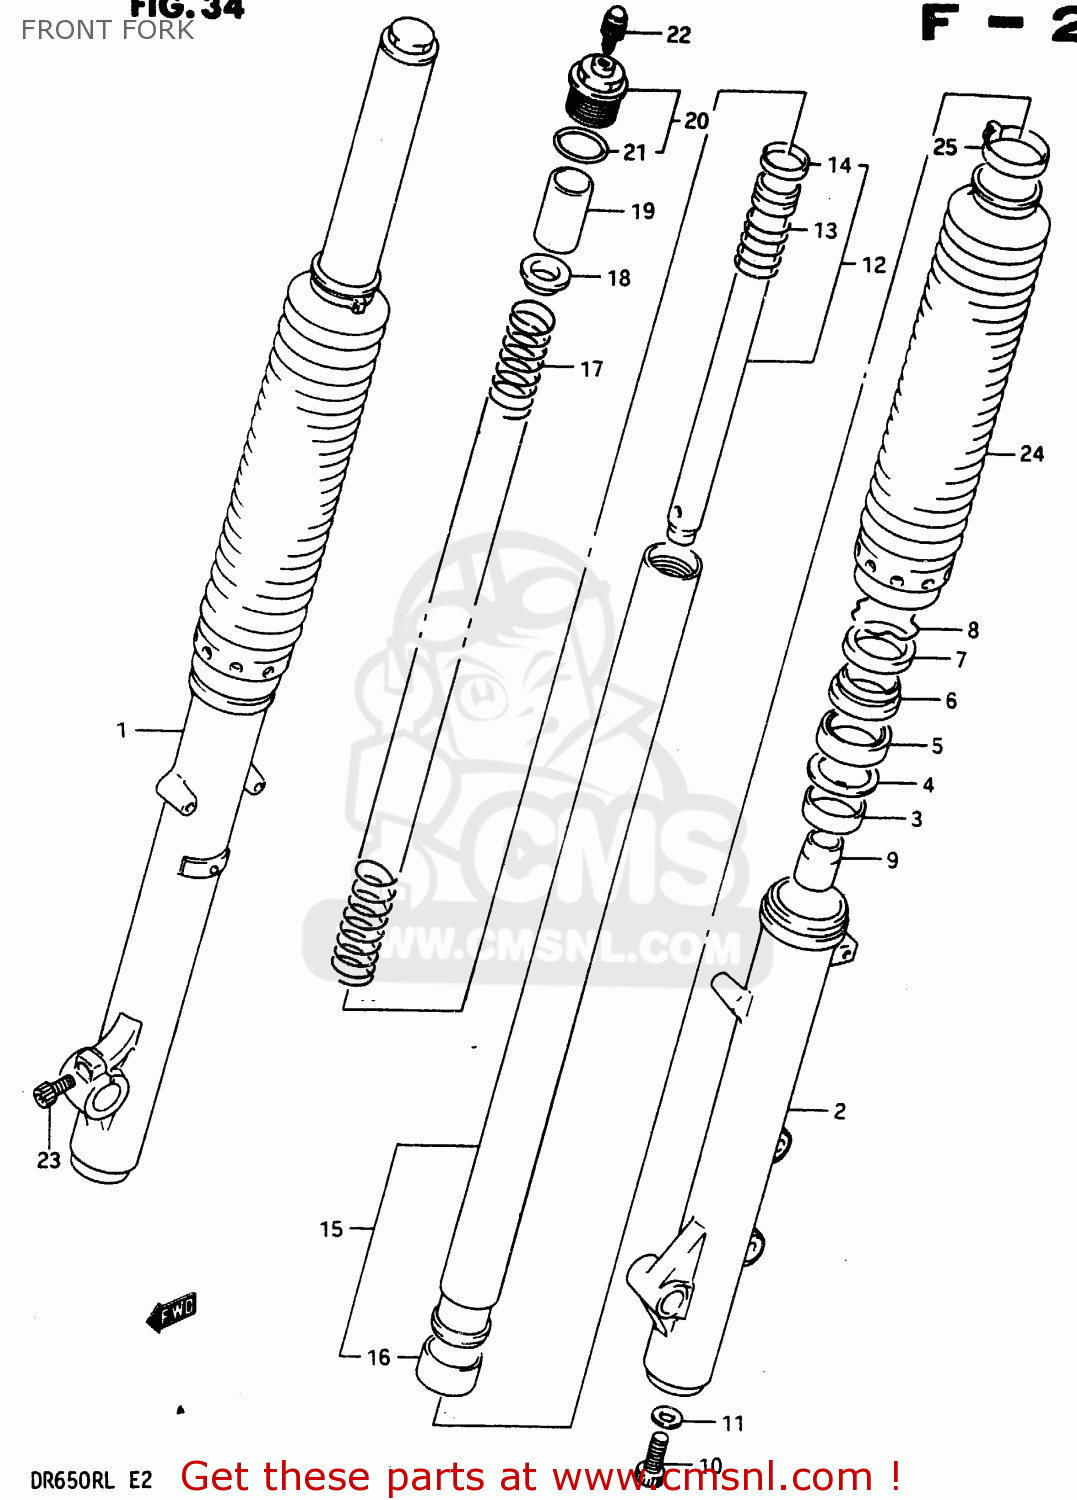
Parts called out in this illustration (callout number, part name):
1	TUBE,OUTER,RIGHT
2	TUBE,OUTER,LEFT
3	METAL,SLIDE
4	WASHER,FORK OIL SEAL
5	SEAL,OIL
6	SEAL,DUST
7	WASHER
8	RING,OIL SEAL STOPPER
9	PIECE,OIL LOCK
10	BOLT(14X25)
11	GASKET (NAS)
12	CYLINDER
13	SPRING,REBOUND
14	RING,FR FORK PISTON
15	TUBE,INNER
16	PISTON
17	SPRING,MAIN
18	GUIDE,SPRING
19	SPACER,SPRING
20	CAP,FORK
21	O-RING
22	CAP,FRONT FORK AIR VALVE
23	BOLT,SOCKET HEAD(8X22)
24	BOOT
25	BAND,BOOT
